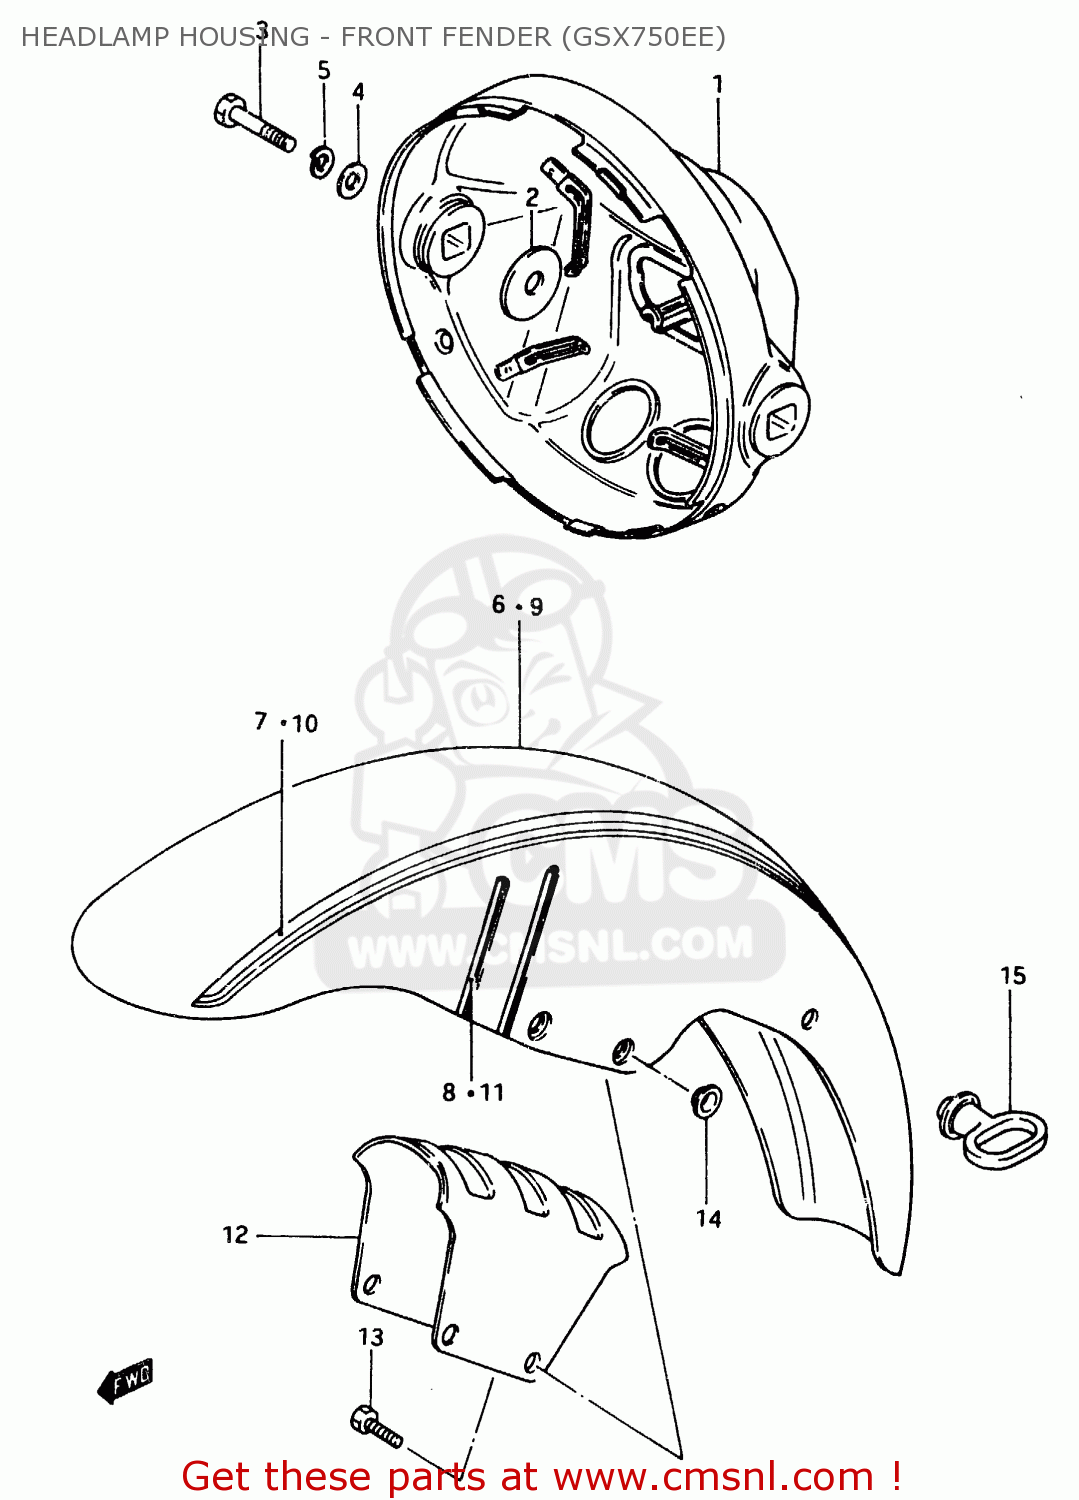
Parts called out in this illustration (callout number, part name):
1	HOUSING,HEADLAMP(BLACK)
2	WASHER (8.5X29X1.6)
3	BOLT
4	WASHER
5	LOCK WASHER
6	FENDER, FRONT (BLUE)
7	TAPE SET
8	DENT,FRONT FENDER
9	FENDER, FRONT (RED)
10	TAPE SET
11	DENT,FRONT FENDER
12	BRACE,FRONT FENDER
13	BOLT
14	WASHER
15	GUIDE,CABLE
